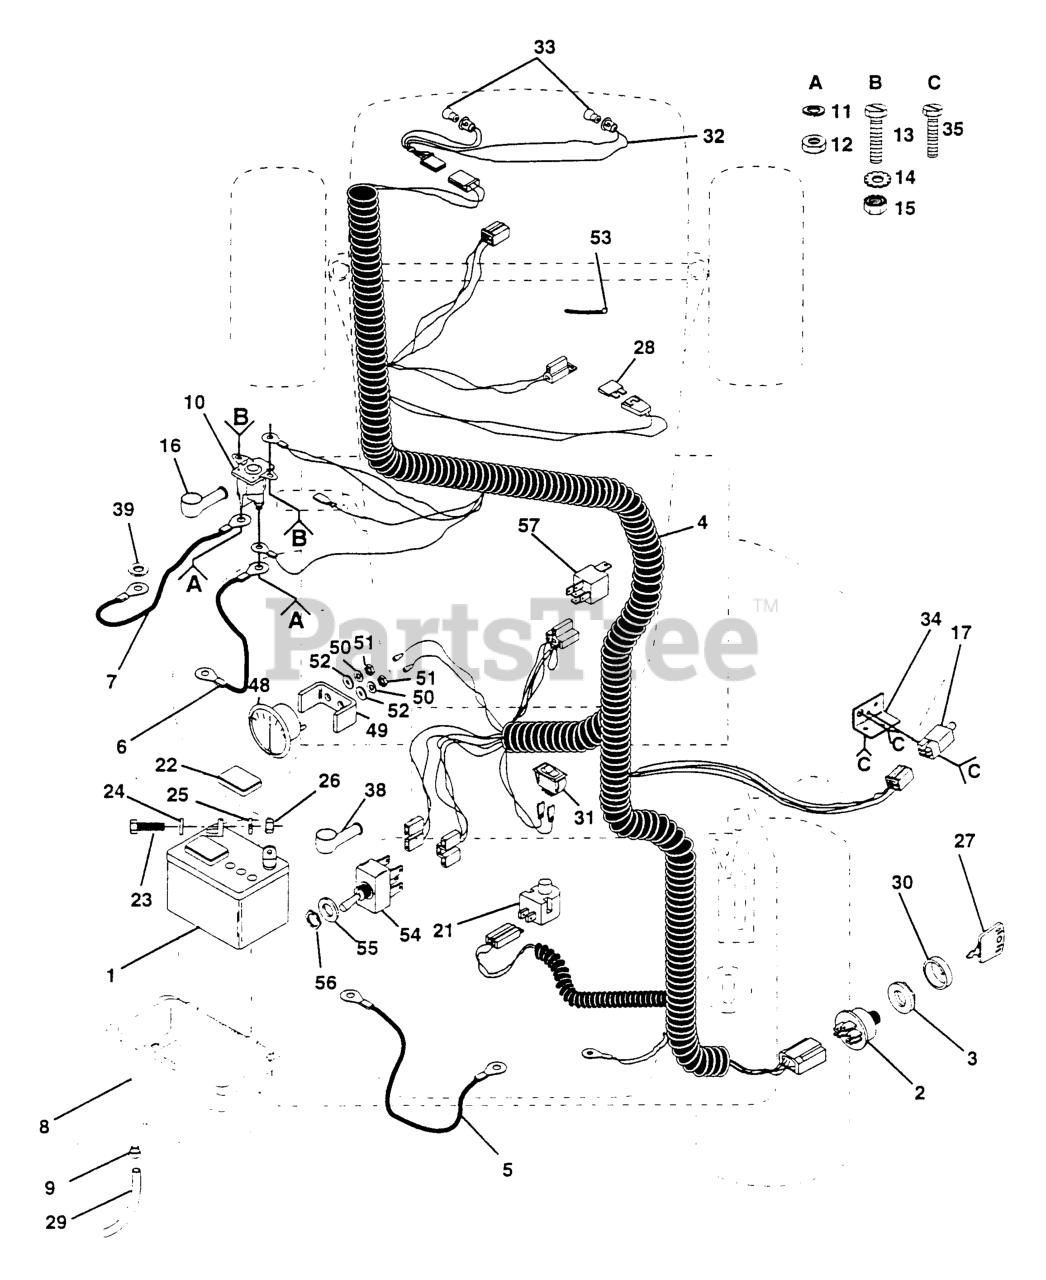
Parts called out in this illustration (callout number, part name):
1	BATTERY
2	SWITCH YTV
3	NUT IGNITION
4	HARNESS IGN
5	CABLE T
6	STEERING CABLE GT
7	CABLE-BATTERY YTV
8	BATTERY CASE W/O LID
9	HOSE CLAMP T
10	SOLENOID
11	LOCKWASHER
12	NUT
13	BOLT
14	Washer Lock Ext Tooth 1/4
15	NUT
16	TERMINAL COVER
17	SWITCH INTERLOCKT
21	RP.SWITCH.PLUNGER.NC.GRAY
22	CAP BATTERY NLA
23	BOLT.HEX.1/4.X.3/4.DICHROMATE
24	WASHER
25	LOCKWASHER
26	NUT
27	KEY.MOLDED.GENERIC
29	TUBE BATTERY DRAIN
30	COVER KEY IGNITIO
32	HARNESS LIGHT SOCKET
33	BULB-LIGHT T
34	BRACKET LT
38	TERMINAL COVER
39	Washer. Lock Int. Tooth 1/4
48	AMMETER.ROUND.15 AMP
49	AMMETER BRACKET
50	LOCKWASHER
53	TIE GUIDE
54	SWITCH
55	WASHER
56	HEX NUT T
57	RELAY.ASSY.T
